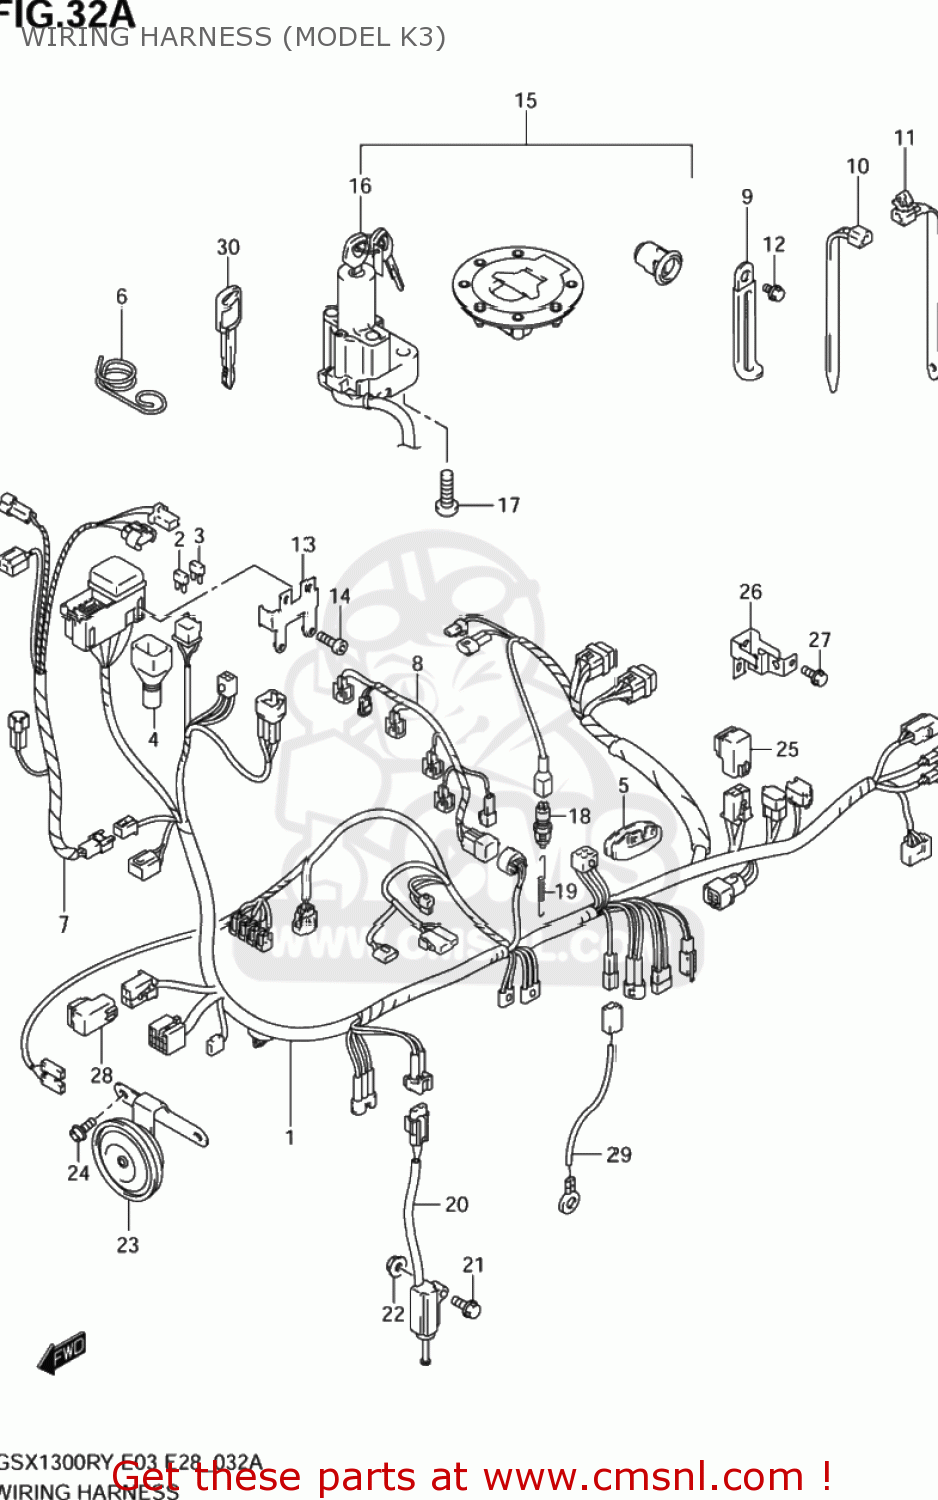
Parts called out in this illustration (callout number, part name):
1	HARNESS,WIRING
2	FUSE(10A)
3	FUSE(15A)
4	COVER,SPEEDOMETER COUPLER
5	PROTECTOR,WIRING HARNESS
6	GUIDE,WIRING HARNESS
7	HARNESS,WIRING NO.2
8	WIRE,INJECTOR LEAD
9	CLAMP(L:65)
10	CLAMP(L:125)
11	CLAMP(L:90)
12	BOLT
13	BRACKET,FUSE BOX
14	BOLT
15	LOCK SET
16	LOCK ASSY,STEERING
17	BOLT(8X20)
18	SWITCH ASSY,STOP LAMP
19	SPRING
20	SWITCH ASSY,SIDE STAND
21	BOLT(8X35)
22	NUT
23	HORN ASSY
24	BOLT
25	RELAY ASSY
26	BRACKET,FUEL PUMP RLY
27	BOLT
28	RELAY ASSY
29	WIRE,OIL PRESSURE SWITCH LEAD
30	KEY,BLANK
